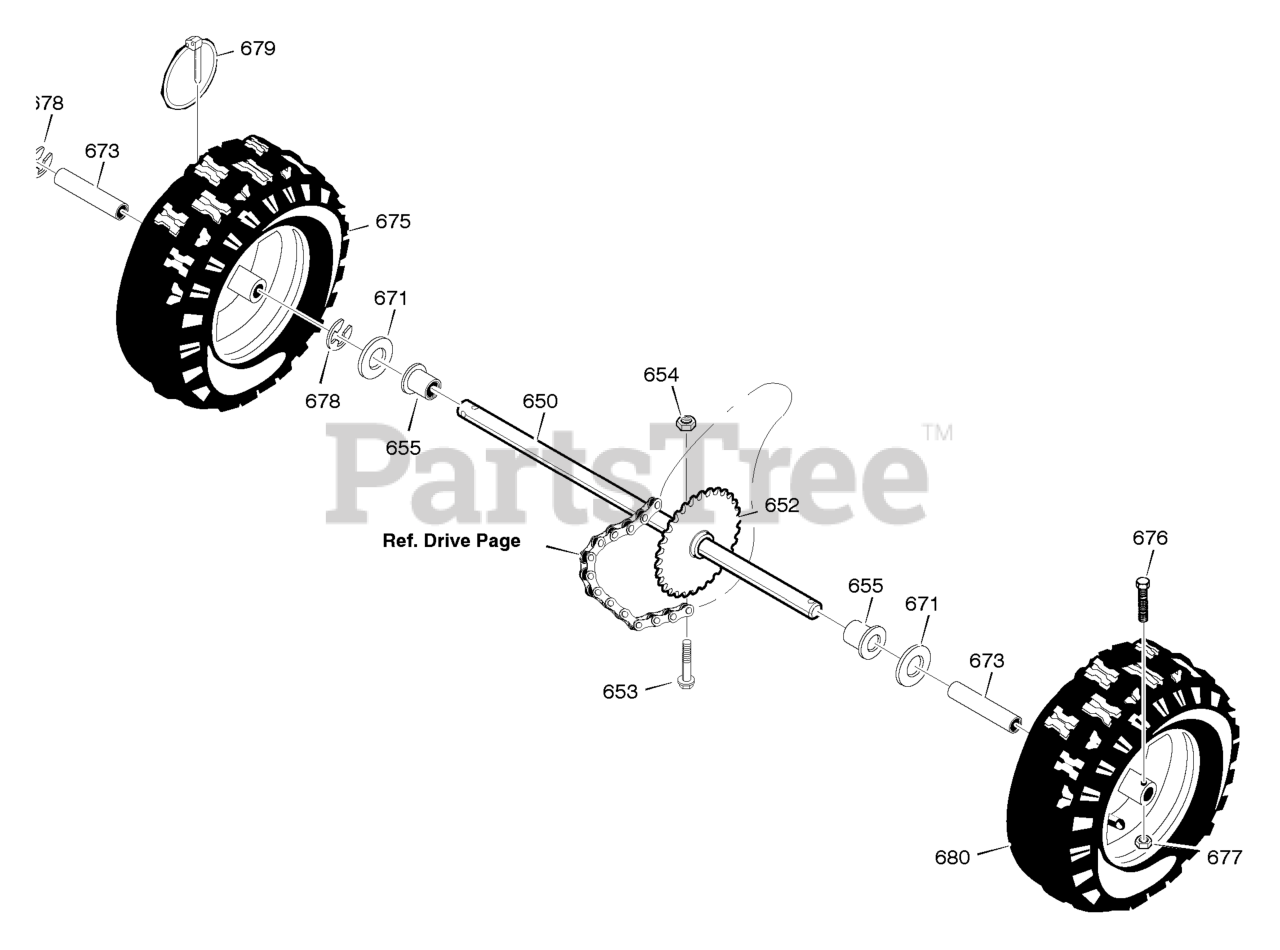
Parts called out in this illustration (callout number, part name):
650	SHAFT, AXLE
652	SPRKT & HUB
653	SCREW, 1/4-20 x 1.75
654	NUT, 1/4-20 HEX NYLOCK
655	BEARING, AXLE
671	FLATWASHER
673	BUSHING, WHEEL
675	TIRE & RIM, RIGHT
676	SCREW, 1/4-20X1.75 HH
677	NUT, 1/4-20 HEX NYLOCK
678	RING, RET
679	PIN, KLIK .25 X 1.38 DIA
680	TIRE & RIM, LEFT
